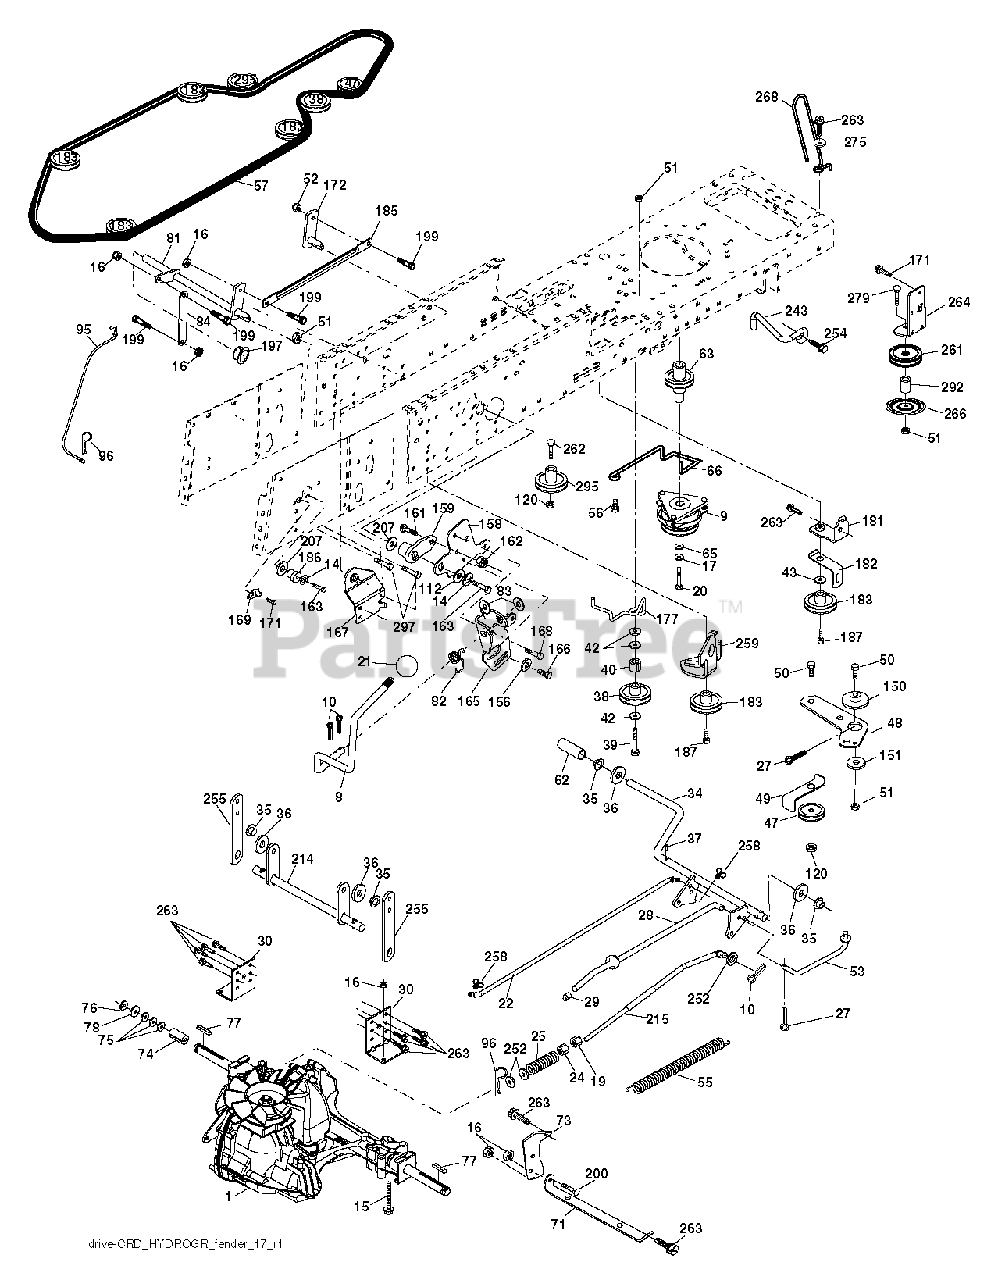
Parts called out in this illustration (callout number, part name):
8	ROD SHIFT FENDER ADJUST LT
9	CLUTCH.ELECTRIC.OGURA.EURO.
10	PIN COTTER
14	LOCKWASHER
15	BOLT HEX 5/16-18 GR 5
16	NUT.71038.31-18.HEX.NYLOCK
19	NUT
20	BOLT HEX 7/16-20X4-1/4"
21	KNOB.DUCKHEAD.1/2
22	ROD
24	NUT
25	SPRING BRAKE ROD
27	COTTER PIN
28	ROD, PARKING BRAKE
29	CAP.BRAKE.PARKING.RED (2 2)
30	BRKT, TRNSXLE MNT 20"
34	SHAFT, FOOT PEDAL
35	BEARING.NYLON
37	DRIVE PIN
38	PULLEY.FLAT
42	WASHER
47	IDLER PULLEY
48	BELLCRANK, CLUTCH
49	RETAIN BELT
50	BOLT.3/8-16X1.50
52	LOCKNUT
53	LINK.CLUTCH.7.66.2005
55	SPRING, RETURN LT
56	SCREW.3/8-16
57	V-BELT 113"
62	PEDAL COVER T
63	PULLEY.ENGINE.CVX.LT
65	LOCKWASHER
66	KEEPER BELT ENGINE
71	STRAP TORQUE LH HYDRO
73	STRAP TORQUE RH HYDRO
74	SPACER AXLE
77	SQUARE KEY
81	ASM.CROSS.SHAFT.REAR.CRD.0510
82	SHIFT SPRING
83	WASHER
84	LINK.PNT.TRANSAXLE.0510.CRD
95	LINK
96	RETAINER M
120	NUT LOCK FLG 3/8-16 UNC
150	BUSHING.BELLCRANK.GRD.DR
151	WASHER 12/32X2X10GA
156	WASHER.SRRTD.5/16
158	BRACKET.SHIFT.MOUNT
159	RB HUB.SHIFT
161	BOLT
162	NUT.CROWNLOCK.1/4
165	BRACKET.PIVOT.LEVER
166	CAPSCREW.HXHD.FLG.5/16-18X.625
167	BRACKET.SUPT.SHIFT.CRD
168	BOLT.SHOULDER.5/16-18X
169	PLATE.FASTENING.CROSS.SHAFT
172	LINK
181	BRACKET
182	BELT GUIDE
183	PULLEY.V-IDLER.
185	LINK
186	HUB.TAPERED.ROUND.CRD
187	BOLT.5/16-18X1.25
197	NYLINER SNAP 5/8" ID
199	BOLT SHOULDER 5/16-18 UNC
207	WASHER NYL
214	LEVER
215	ROD
243	BRACKET, ANTI-ROTATION
252	WASHER
254	SCREW 3/8-16X1
255	SHAFT
258	CLIP RETAINER
259	BRACKET
261	FLAT IDLER PULLEY
263	SCREW, 3/8-16X3/4
264	BRACKET.IDLER
266	PROTECTOR
268	GUARD MUFFLER
275	WASHER
292	SPACER
295	PULLEY IDLER COMPOSITE
297	SCREW LT.3/8-46X5/8
